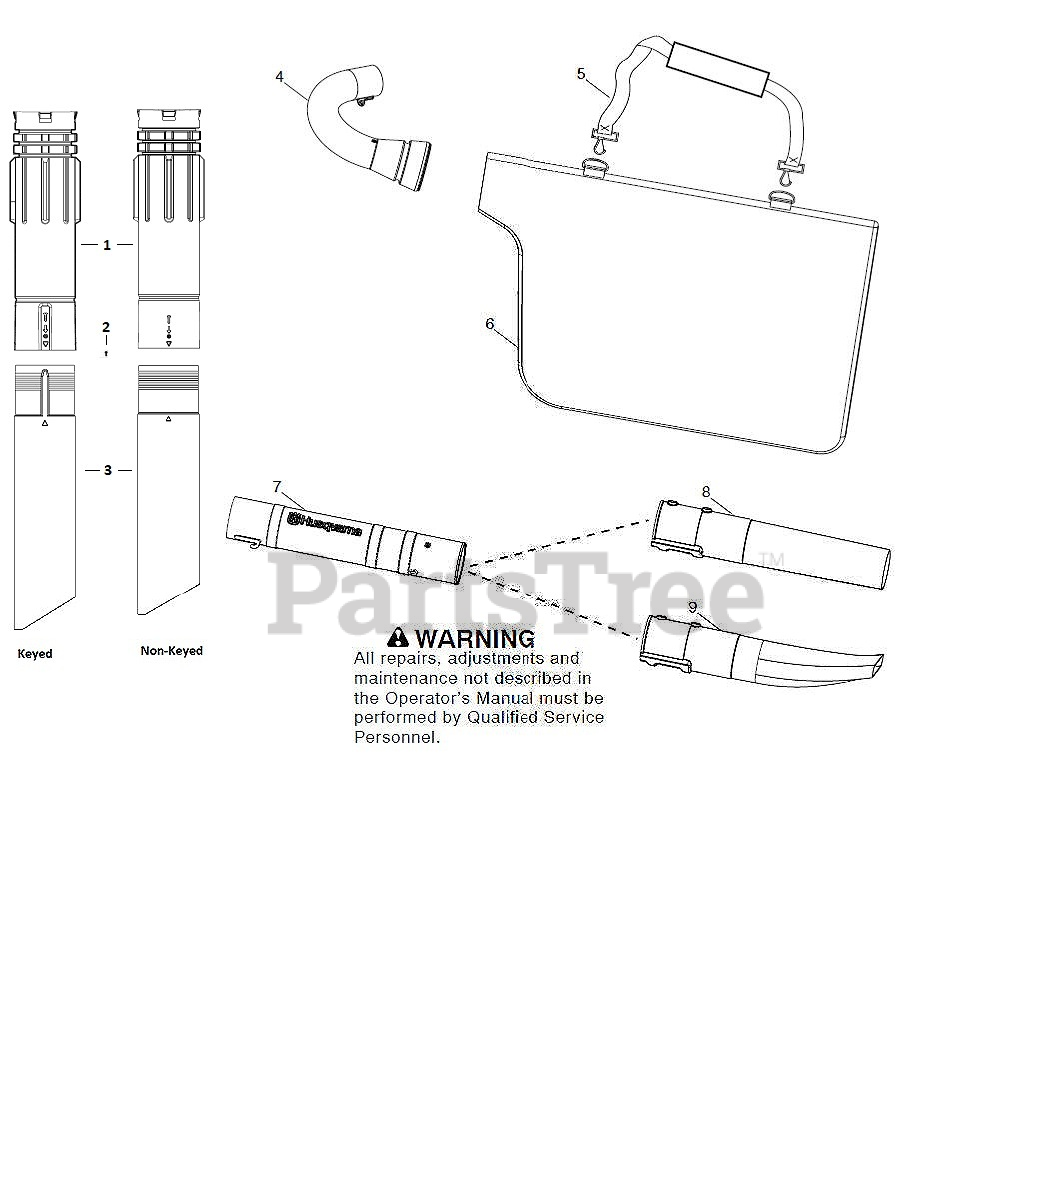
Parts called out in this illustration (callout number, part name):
1	ASSY, UPPER VAC TUBE
1	VAC TUBE
2	SCREW
4	TUBE ELBOW VACUUM GRAY
5	STRAP SHOULDER
6	Bag
7	TUBE UPPER BLOWER HUS GRAY
8	TUBE, LOWER
9	FLARE, LOWER TUBE
